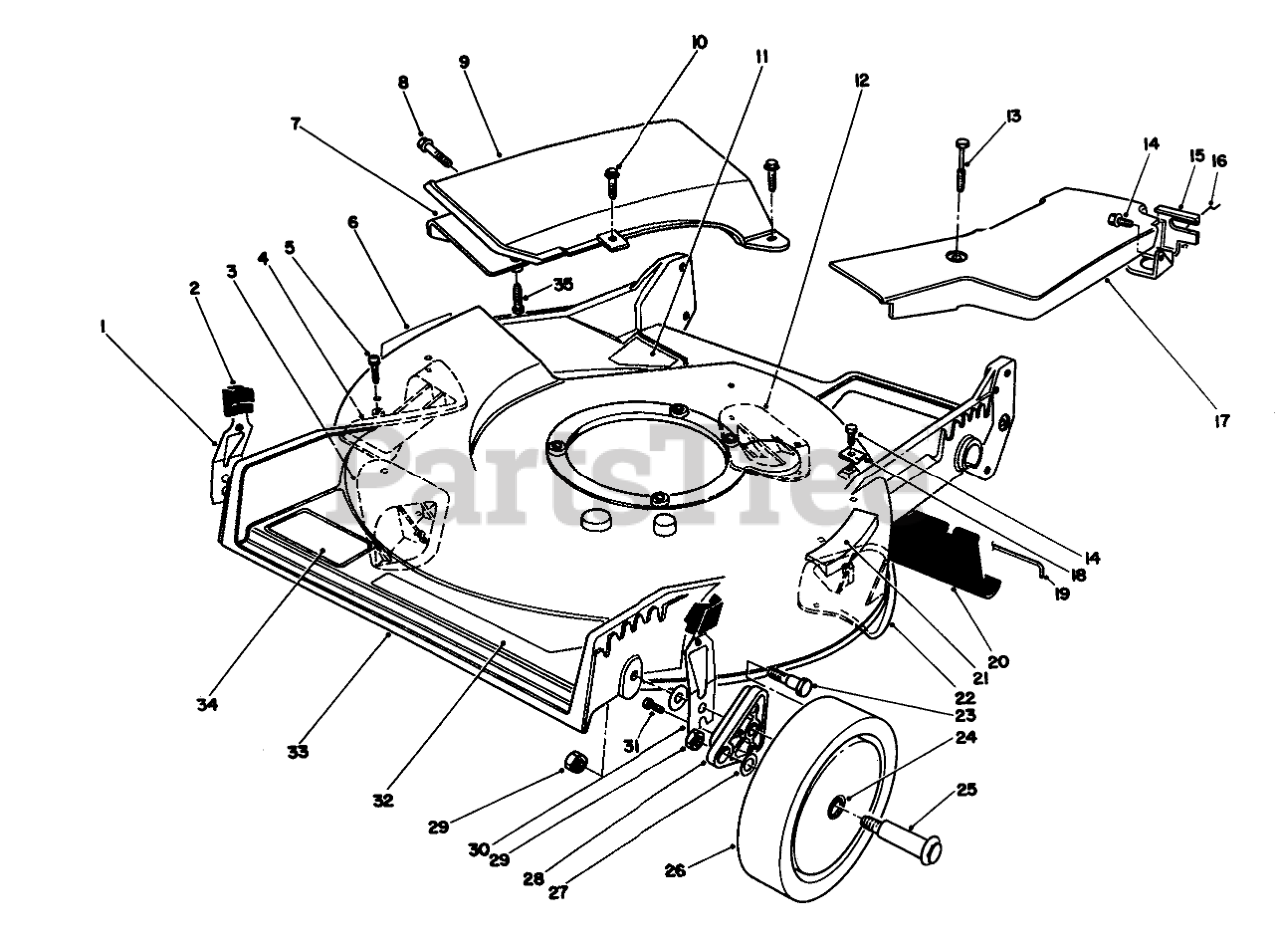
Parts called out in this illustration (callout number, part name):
1	RH SPRING ARM ASSEMBLY
2	KNOB-ARM
3	KICKER
4	KICKER
5	SCREW-PPH
6	DECAL-DANGER
7	Deflector-Recycler
8	SCREW AND WASHER ASM
9	Cover Assembly (Incl. Ref. #7 & 35)
10	SCREW-HWH
11	DECAL - DANGER
12	KICKER
13	SCREW-HHFTF
14	SCREW-HWHTF
15	Bracket-Adj. Trac
16	RETAINER-CABLE
17	BELT COVER
18	CLAMP-CABLE
19	ROD-SHIELD
20	SHIELD-TRAILING
21	STEP PAD DECAL
22	KICKER
23	SCREW-SHOULDER
24	BUSHING
25	WHEEL BOLT
26	Wheel & Tire Assembly (Incl. Ref. #24)
27	WASHER
28	ARM-PIVOT, FRONT
29	Nut
30	LH SPRING ARM ASSEMBLY
31	SCREW-HWH
32	DECAL - DECK
33	Housing Assembly (Incl. Ref. #3-6, 11, 12, 22, & 32)
34	DECAL
35	Screw-Plastite
